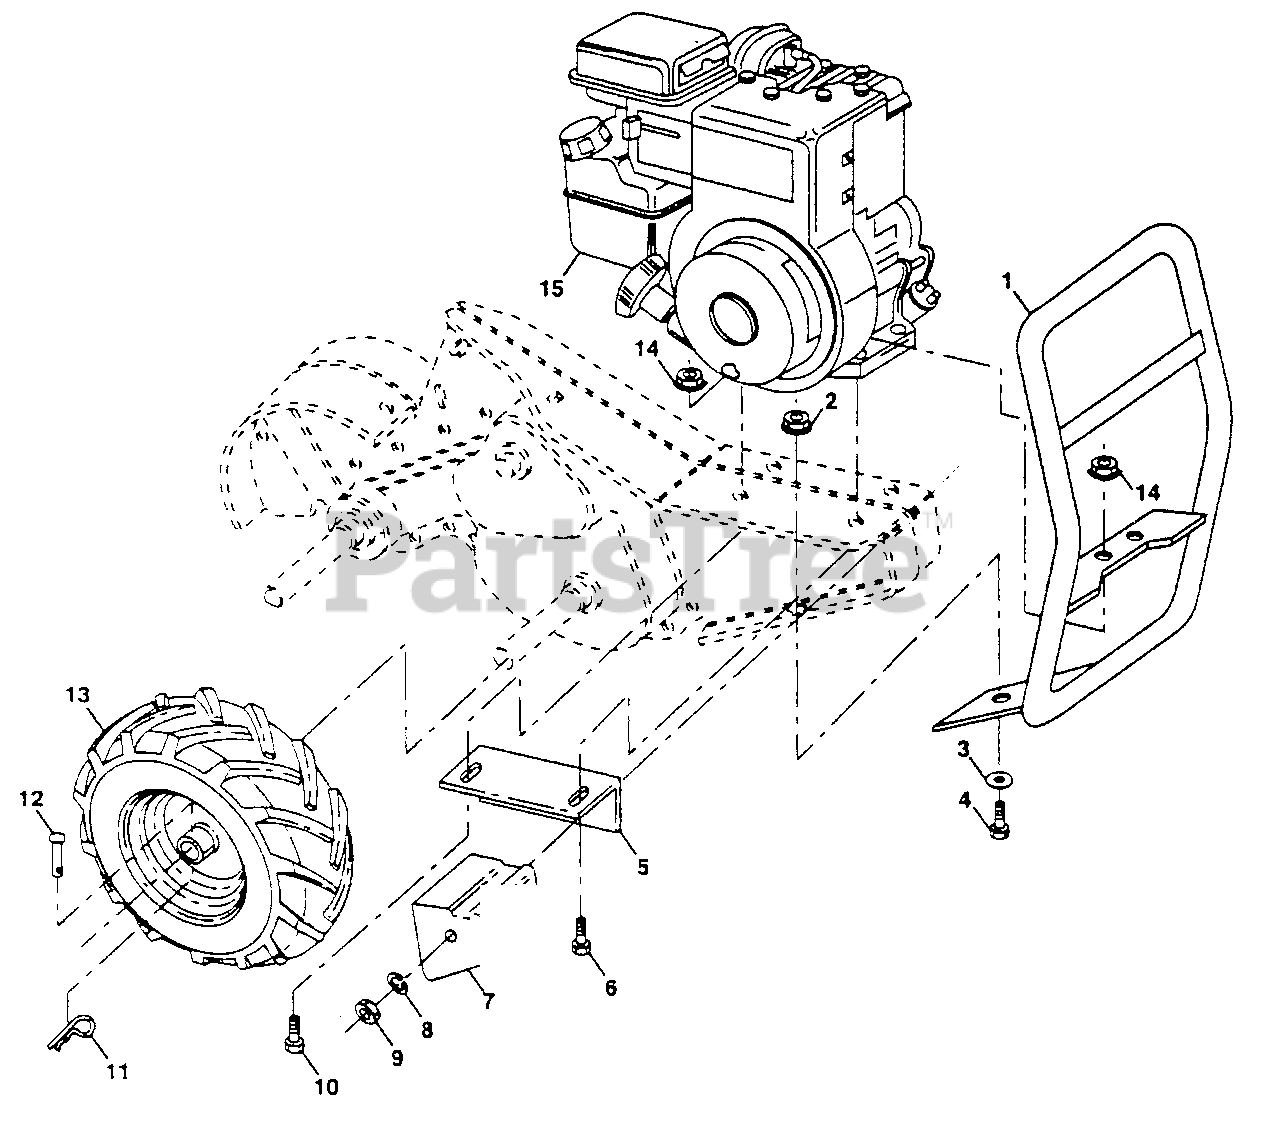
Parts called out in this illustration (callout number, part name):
1	Bumper (AYP part number)
2	Locknut, Hex, Flange 5/16-18 (AYP part number)
3	Washer 11/32 x 11/16 x 16 Ga. (AYP part number)
4	Bolt, Hex 5/16-18 x 3/4 (AYP part number)
5	Bracket, Reinforcement (AYP part number)
6	Bolt, Hex 5/16-18 x 2 (AYP part number)
7	Counter Weight, R.H. (AYP part number)
8	Washer, Lock 3/8 (AYP part number)
9	Nut, Hex 3/8-16 (AYP part number)
10	Bolt, Hex 5/16-18 x 1-1/2 (AYP part number)
11	Clip, Hairpin (AYP part number)
12	Rivet, Drilled (AYP part number)
13	Tire (AYP part number)
14	Nut, Keps 5/16-18 (AYP part number)
